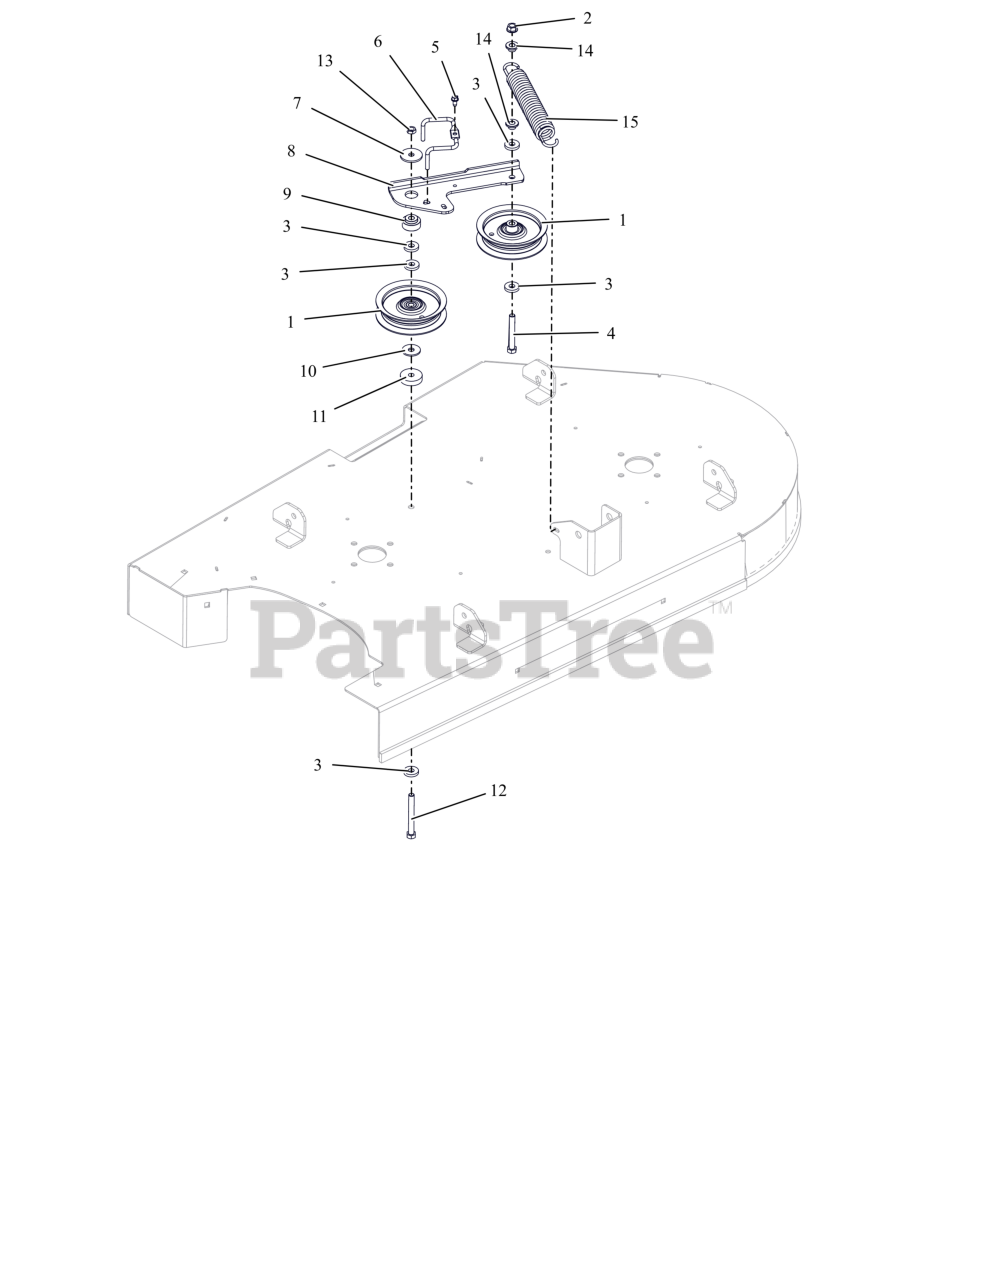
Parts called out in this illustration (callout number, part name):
1	IDLER, FLAT - 4.06" X .75"
2	NUT-LK-CTR-FLG .375-16 GF ZCC
3	WSHR, FLT .406X1.00X.188 ZCC
4	BLT, HEX .38-16X2.75 G5 ZCC
5	SCR-TAP .25-20X.50 HWH ZCC
6	WIREFORM, BELT FINGER
7	WSHR, FLT .380X1.50X.125 ZCC
8	ARM- IDLER EDGE
9	BSHG- FLANGED
10	WSHR FL STL .406X1.25X.10ZC120
11	SPACER, .39 X 1.50 X .380
12	BLT, HEX .38-16X3.25 G5 ZCC
13	NUT-LK-CTR-JAM .375-16 GB ZCC
14	BSHG-FLG .385X.500X.875X.406
15	SPRG, EXTENSION
